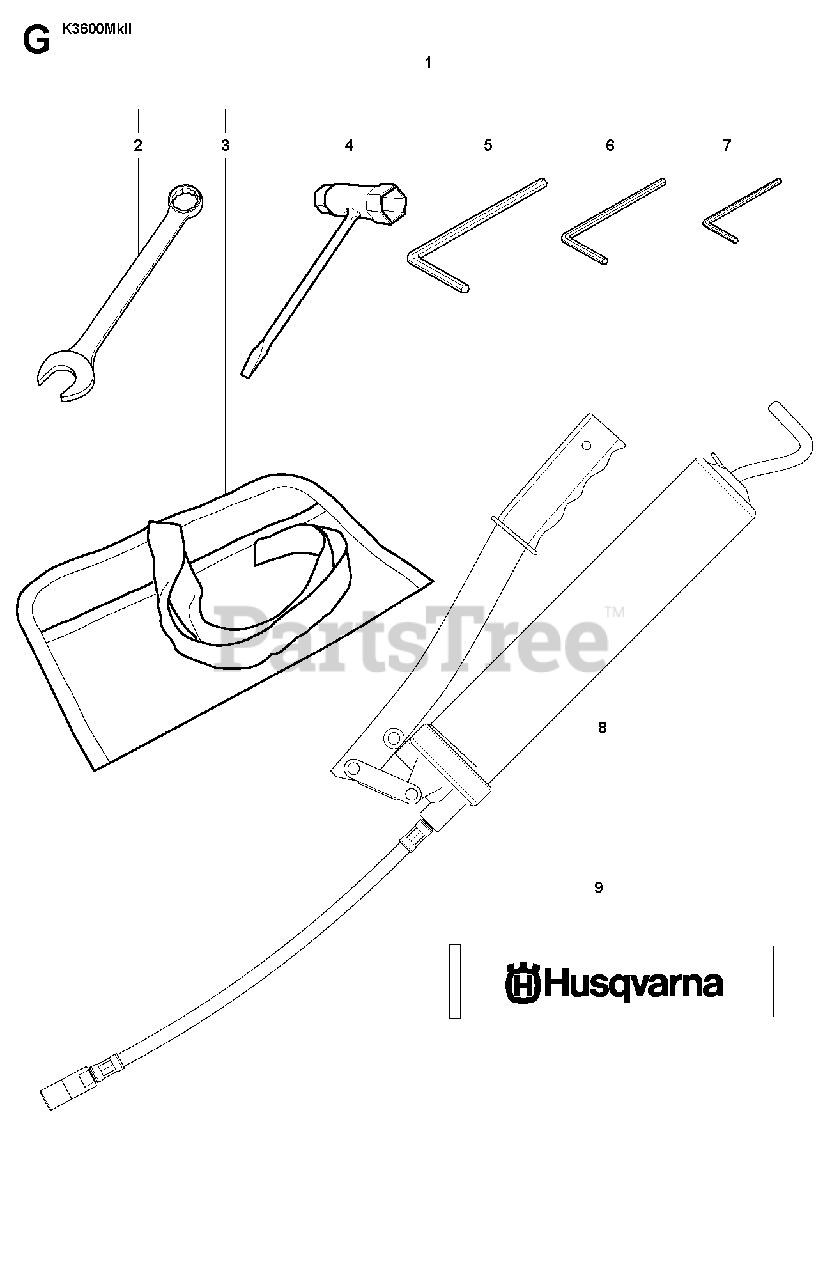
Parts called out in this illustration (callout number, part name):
1	TOOLIncl. 2, 3, 4, 5, 6, 7
4	COMBINATION WRENCH13-19mm
9	GREASE
